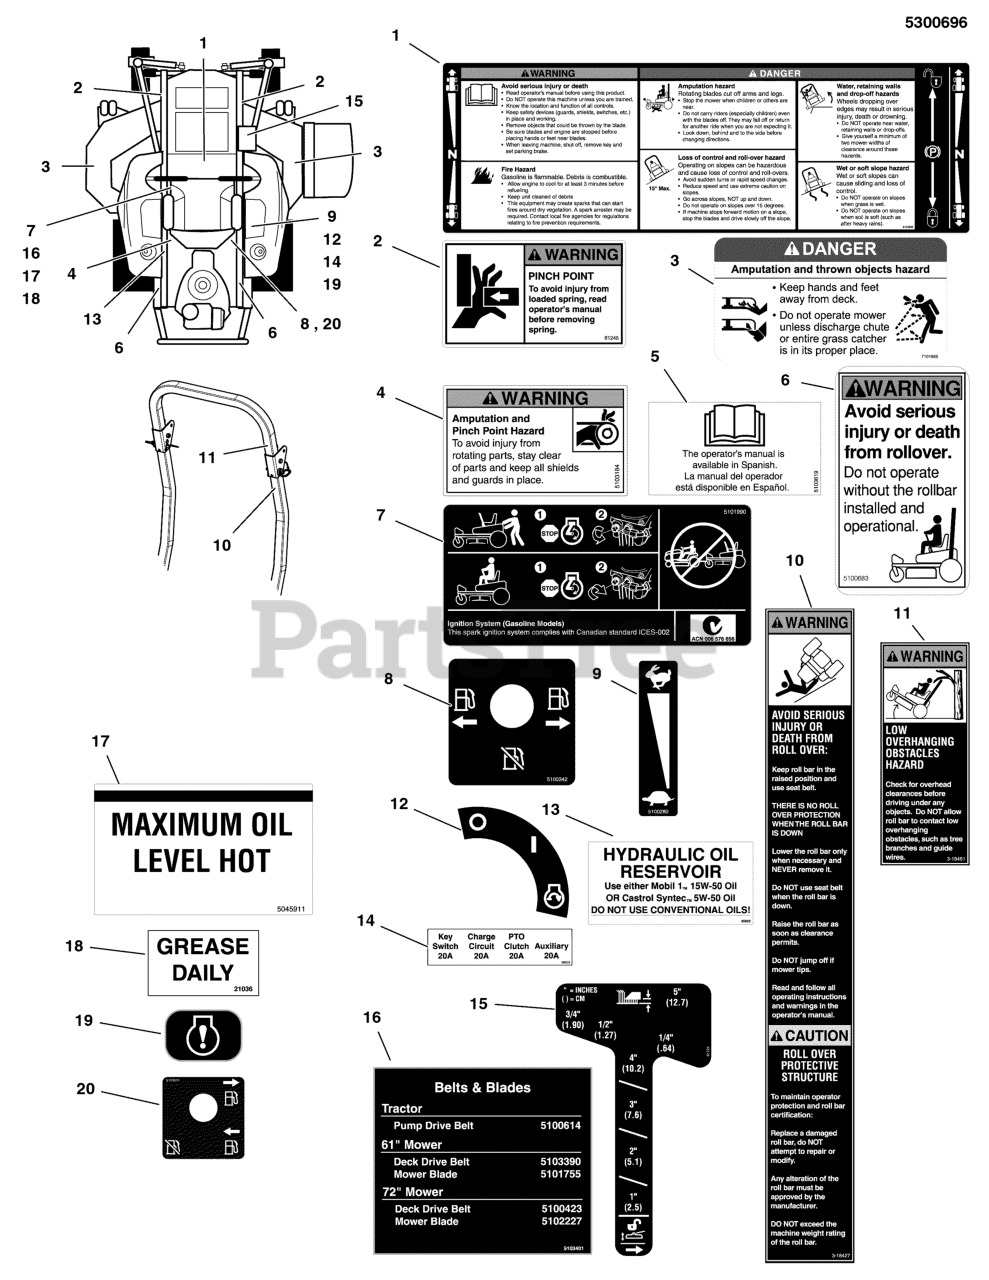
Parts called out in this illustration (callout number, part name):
1	DECAL, MAIN SAFETY
2	DECAL, PINCH POINT
3	DECAL, DANGER DO NOT OPERATE W/O DEFLECT
4	DECAL, WARNING, HAND IN BELT, ENG ONLY
5	DECAL, MANUAL AVAIL IN SPANISH
6	DECAL, WARNING, ROLL BAR
7	DECAL, CZT HYRDO RELEASE
8	DECAL, FUEL VALVE
9	DECAL, THROTTLE CONTROL
11	DECAL, WARNING OVERHANG, ROPS
12	DECAL, IGNITION SWITCH
13	DECAL-OIL RESERVOIR
14	DECAL, FUSE LOCATION
15	DECAL-HEIGHT CITATION
16	DECAL, BELT & BLADE, IS3100Z iCD
17	DECAL, MAX OIL LEVEL
18	DECAL, GREASE DAILY
19	DECAL, INDICATOR LAMP
20	DECAL, FUEL VALVE, DFI
